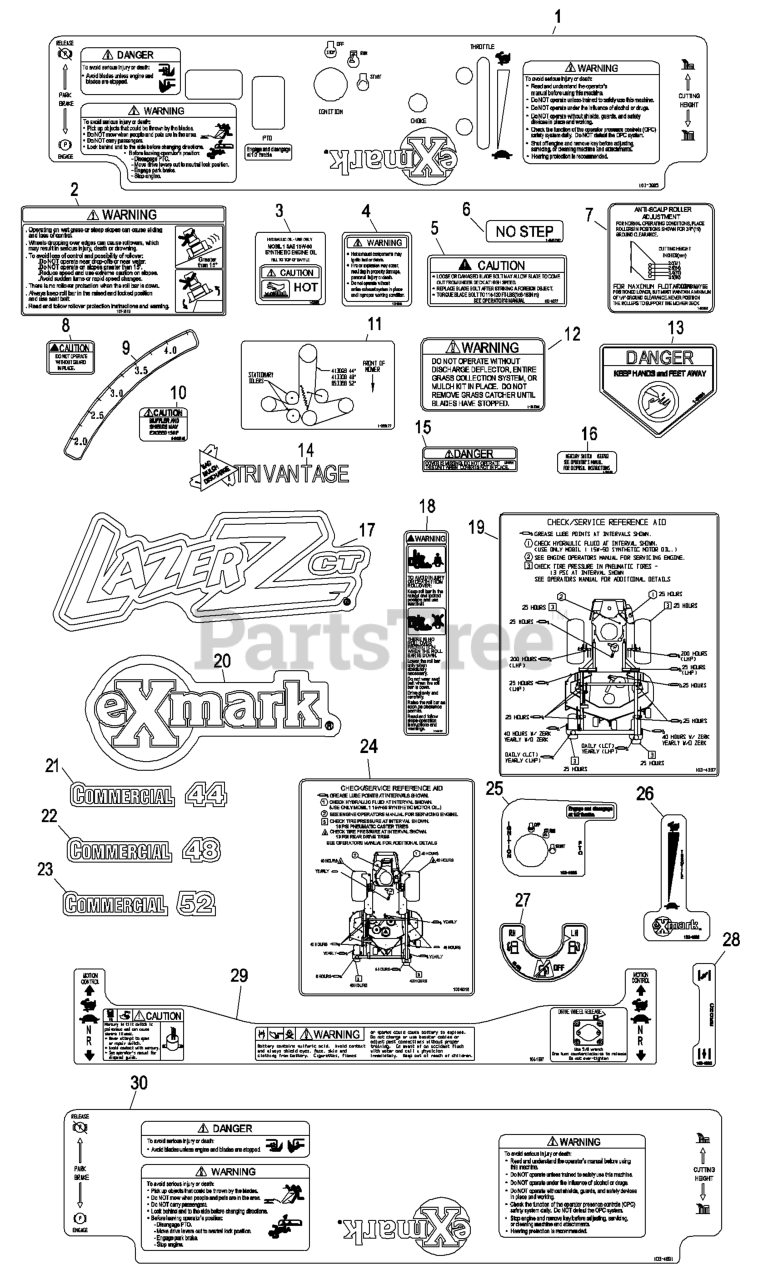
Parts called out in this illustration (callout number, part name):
1	DECAL,CONSOLE LHP
2	DECAL-WARNING
4	DECAL-EXHAUST
5	DECAL,BOLT TORQUE
6	DECAL,NO STEP
7	DECAL,ANTISCALP
8	DECAL-GUARD
9	DECAL-DECK HEIGHT, INNER
12	DECAL-WARNING, DISCHARGE
13	DECAL-DANGER
15	DECAL-COVER, MISSING
16	DECAL-SWITCH, MERCURY
17	DECAL,LCT MODEL
18	DECAL-WARNING, FOLDING RO
20	DECAL,EXMARK LOGO
21	DECAL,COMMERCIAL 44
22	DECAL,COMMERCIAL 48
23	DECAL,COMMERCIAL 52
25	DECAL,IGNITION/PTO
26	DECAL,THROTTLE
27	DECAL-VALVE, FUEL
28	DECAL,CHOKE
30	DECAL,CONSOLE LHP
